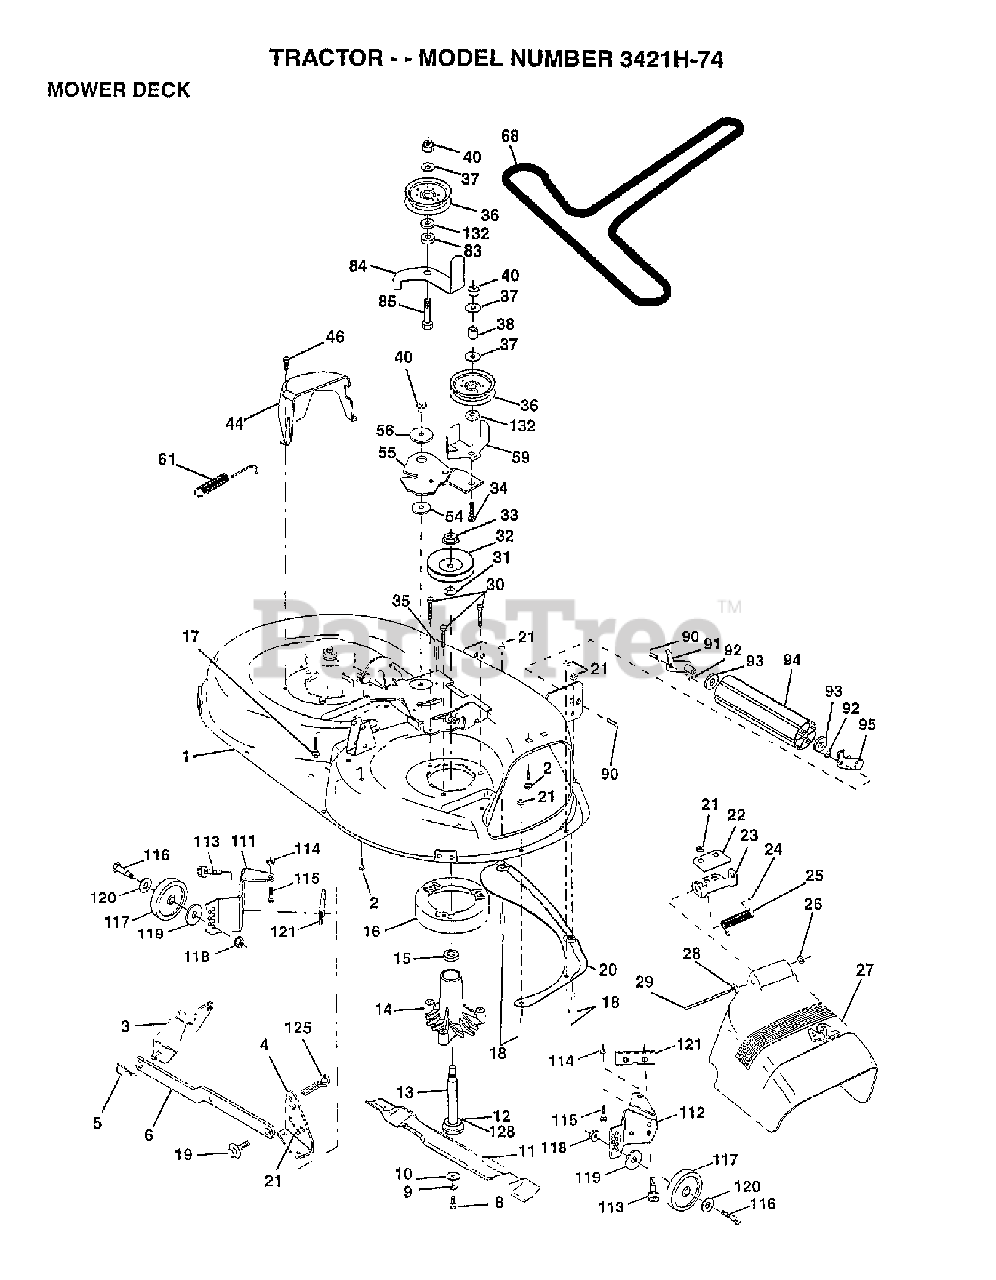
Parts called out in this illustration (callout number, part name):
2	BOLT
3	BRKT ASM SWAY BAR
4	BRKT DECK SW BAR
5	RETAINER SPRING
8	BLADE BOLT
10	WASHER.BLADE
11	BLADE 42" LOW-LIFT VENT DECK
12	BEARING.BALL.#6204.(MANDREL)
13	SHAFT ASM VENT
14	HSG MANDREL
17	BOLT CARRIAGE
18	BOLT
19	BOLT SHD 5/16-18
21	LOCKNUT
23	DEFLECTOR BRACKET
24	CAP-SLEEVE LT
25	DEFLECTOR SPRG T
26	NUT PUSH M
27	SHIELD.DEFLECTOR.MOWER.42".BLK
28	WASHER
29	ROD.HINGE
30	Hex Washer Head Bolt, .313-18 X 1.19
31	WASHER
32	PULLEY/MANDREL
35	FASTENER.XMAS.TREE
36	IDLER-FLAT GT
38	IDLER SPRING SPACER
40	LOCKNUT
44	MANDREL GUARD LH
46	SCREW.1/4-20X5/8
59	GUARD, BELT
61	SPRING EXTENSION
68	V-BELT TRIPATH
84	KEEPER.BELT.IDLER
90	BOLT
91	Roller Bracket Assembly, LH
92	NUT
94	MANUAL, OPERATOR
113	Screw, Lt
116	BOLT
117	GUAGE WHEEL GT
118	LOCKNUT
119	WASHER
121	BRACKET.EXTRUDED.GAGE.WHEEL
128	WASHER FELT
132	WASHER GT
